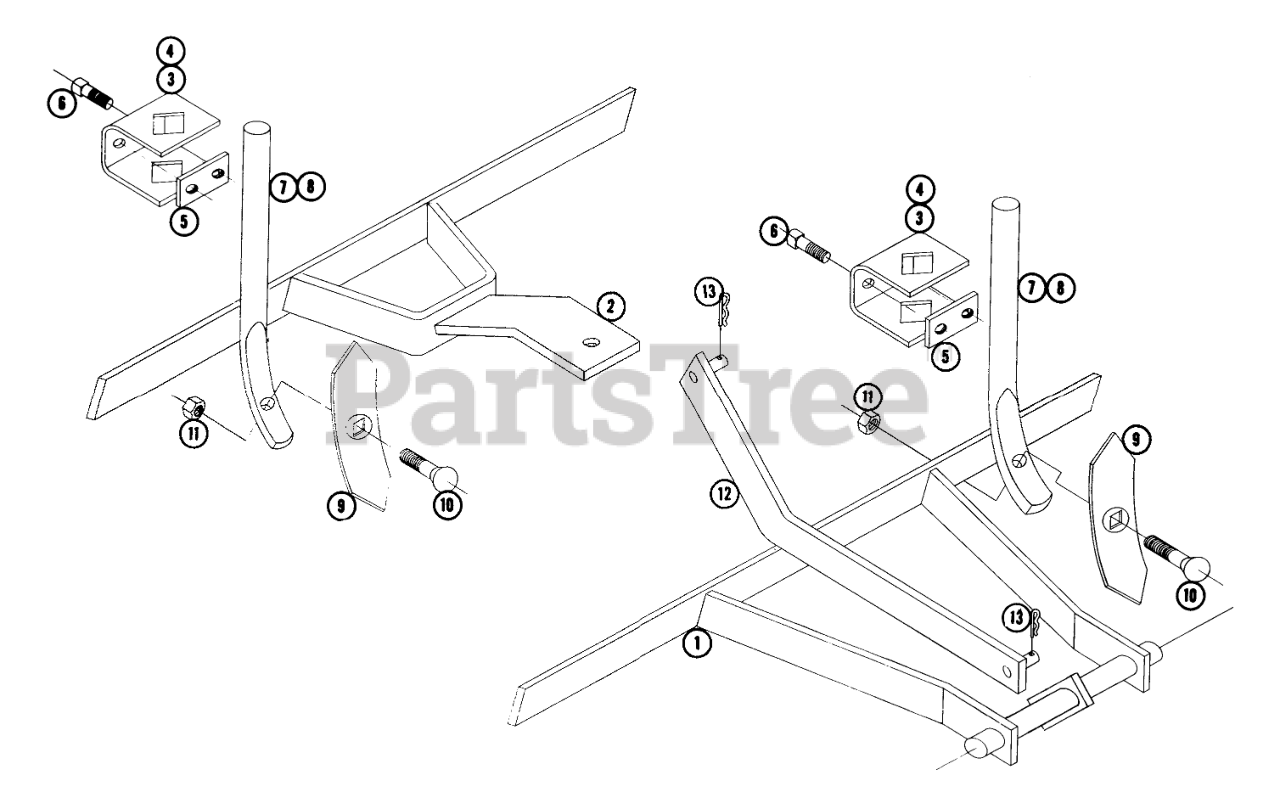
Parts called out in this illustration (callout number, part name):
1	Ass-y. Frame-Front
2	Rear Frame W/A
6	Set Screw, 3/8-16 x 1-1/4
7	Ass-y. Standard Shovel
10	Plowbolt 3/8-16 x 1-1/2
13	Hairpin
